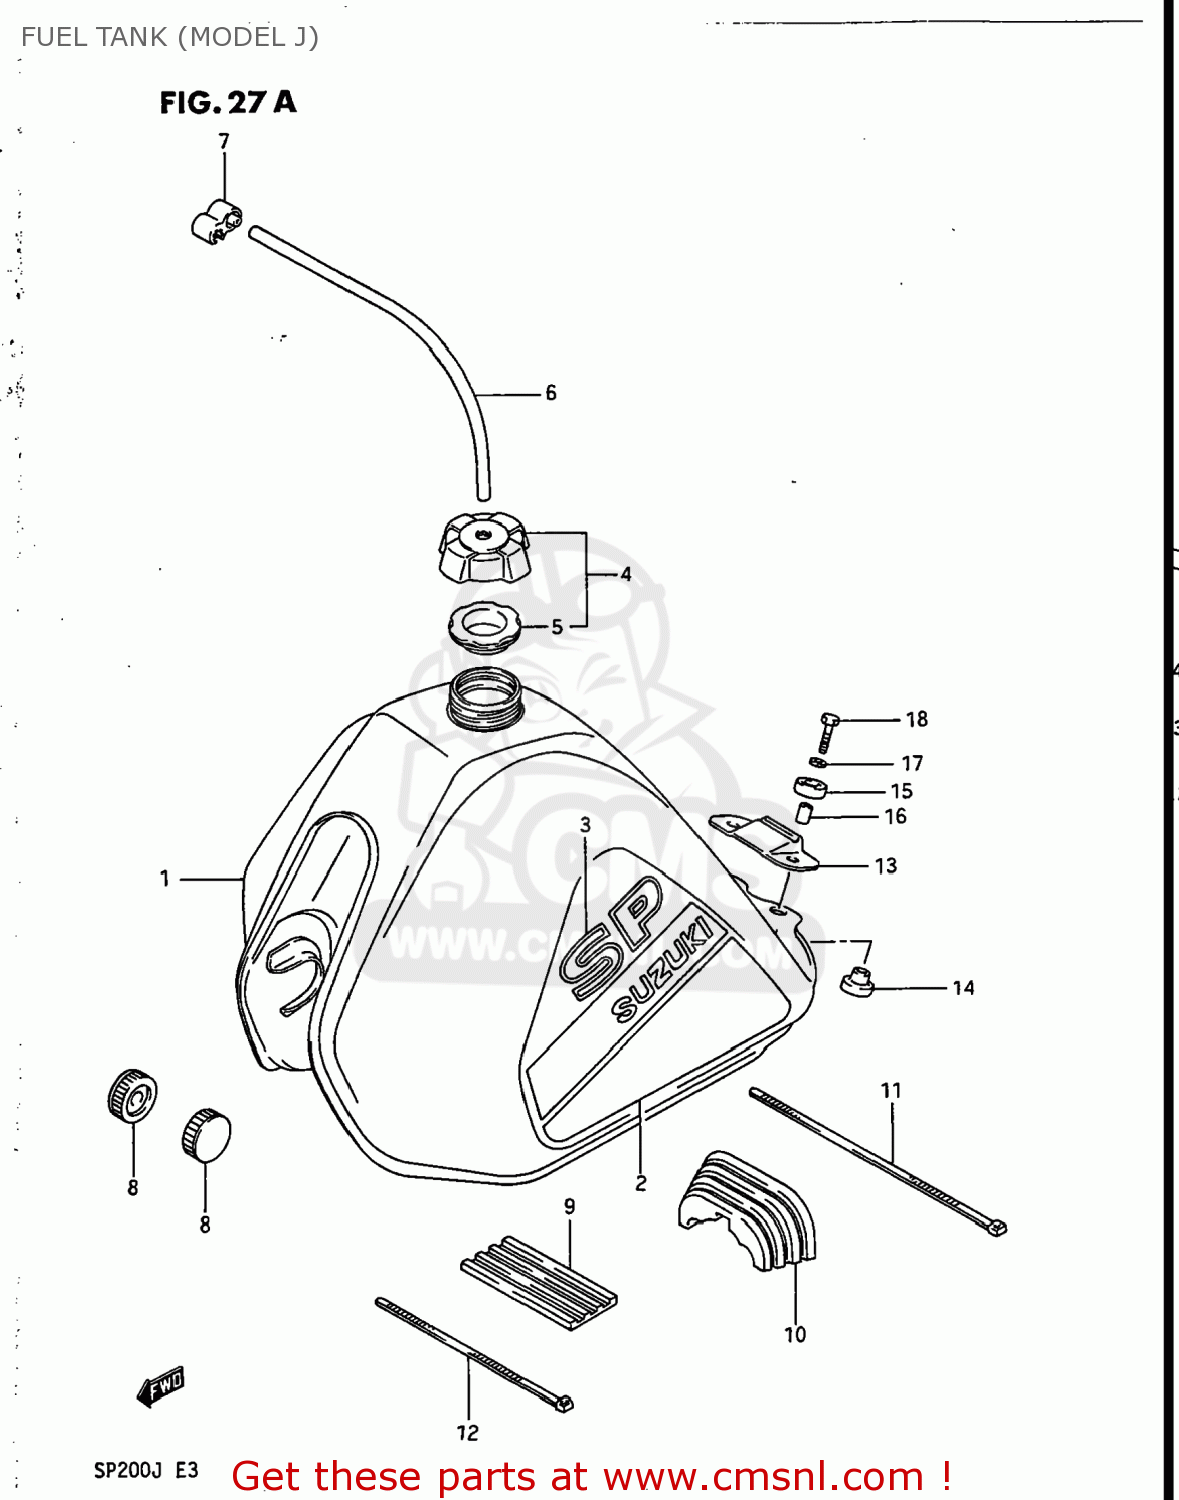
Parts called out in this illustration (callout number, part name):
1	TANK ASSEMBLY,FUEL (RED)
2	TAPE SET,FUEL TANK
3	EMBLEM,FUEL TANK
4	CAP SET,FUEL TANK
5	GASKET (NAS)
6	HOSE
7	CLAMP,FUEL TANK BREATHER HOSE
8	CUSHION
9	CUSHION,FUEL TANK UPR FR
10	CUSHION,FUEL TANK RR
11	CLAMP(L:250)
12	CLAMP
13	PLATE,SEAT FR HOOK
14	CUSHION
15	CUSHION
16	SPACER
17	WASHER,LOCK
18	BOLT
